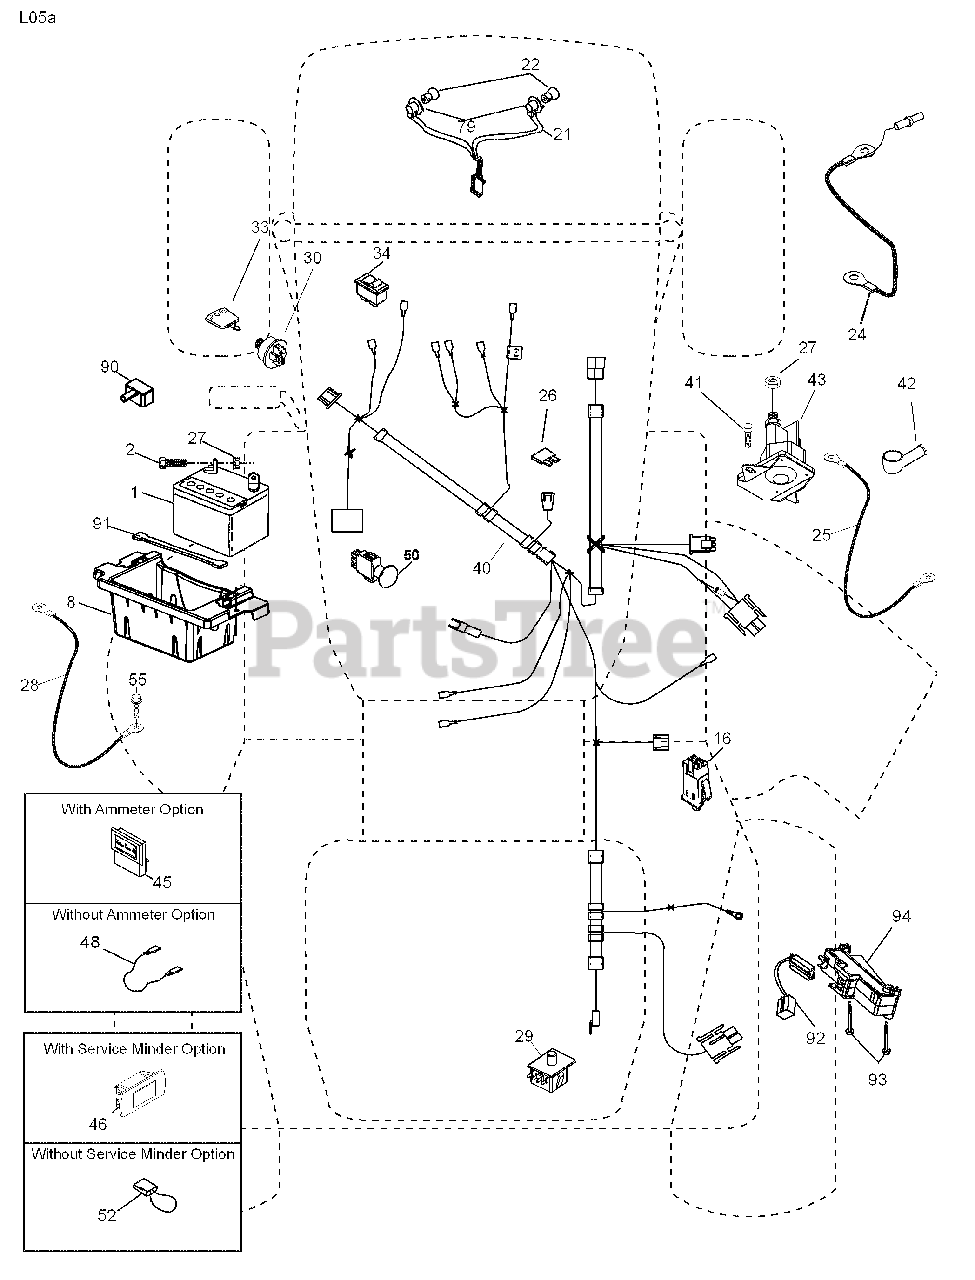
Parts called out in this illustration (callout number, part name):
1	Battery
2	Bolt Hex Hd 1/4-20 unc x 3/4
8	Box Battery
16	Switch Interlock
21	Harness Socket Light
22	Bulb, Light #1156
24	Cable Battery
25	Cable Battery 6 Ga. Red w/16 Wire
27	Nut Keps Hex 1/4-20 unc
28	Cable Ground 21" Blk 6 Ga.
29	Switch Seat
30	Switch Ign
34	Switch Light/Reset
40	Harness Ign
41	Bolt Fin Hex 1/4-20 unc x 1/2
42	Cover Terminal Red
43	Solenoid
46	Hourmeter Snap-In
50	Switch PTO
55	Screw Thdrol 5/16-18 x 1/2
79	Socket Asm. Bulb
90	Cover Terminal
91	Strap Battery
92	Harness Pigtail Console
93	Screw Plastite 10-14 x 2.0
94	Module Reverse ROS
101	Harness Clutch EVX
